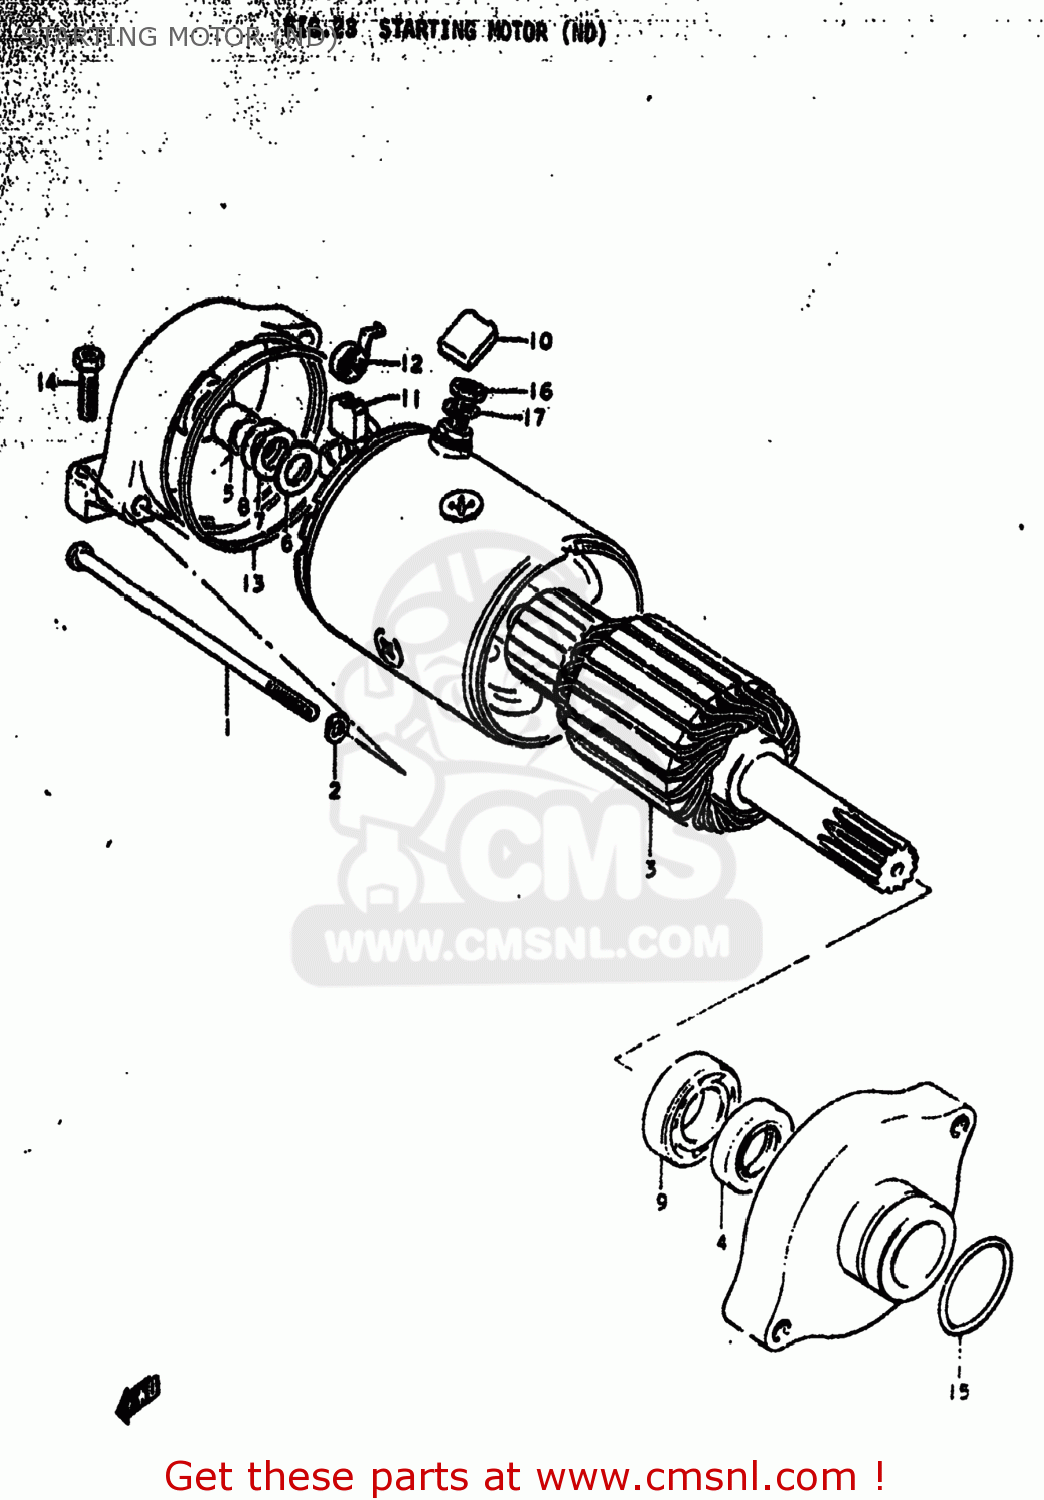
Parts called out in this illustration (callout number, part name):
1	BOLT
2	LOCK WASHER
3	ARMATURE
4	SEAL,OIL
5	BUSHING
6	SHIM, (1)
7	SHIM, (2)
8	SHIM, (3)
9	BEARING
10	BRUSH(-)
11	BRUSH(-)
12	SPRING
13	GASKET
14	SCREW
15	O RING(D:2,ID:24.5)
16	NUT 6MM
17	LOCK WASHER
